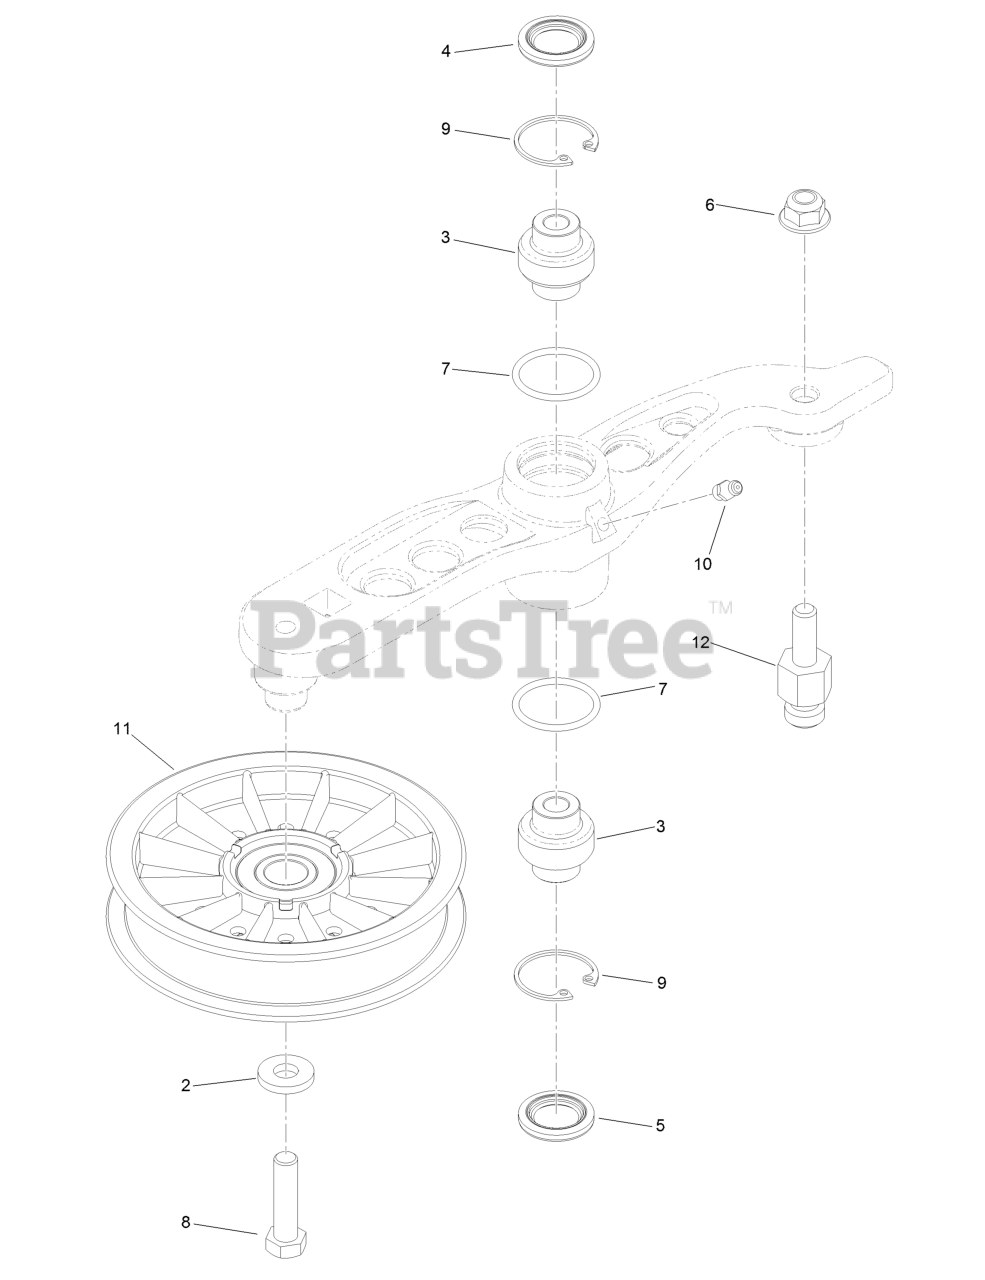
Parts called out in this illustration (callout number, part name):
3	Bearing-Spherical
4	Seal-Lip, Double
5	Seal-Single Lip
6	Nut-Nyloc 3/8-16 Flg
8	Screw-HH 3/8-16 X 1 1/2
9	Ring-Retaining
10	Zerk-1/4-28 Str
11	Pulley-Idler
12	Pin-Anchor, Spring
